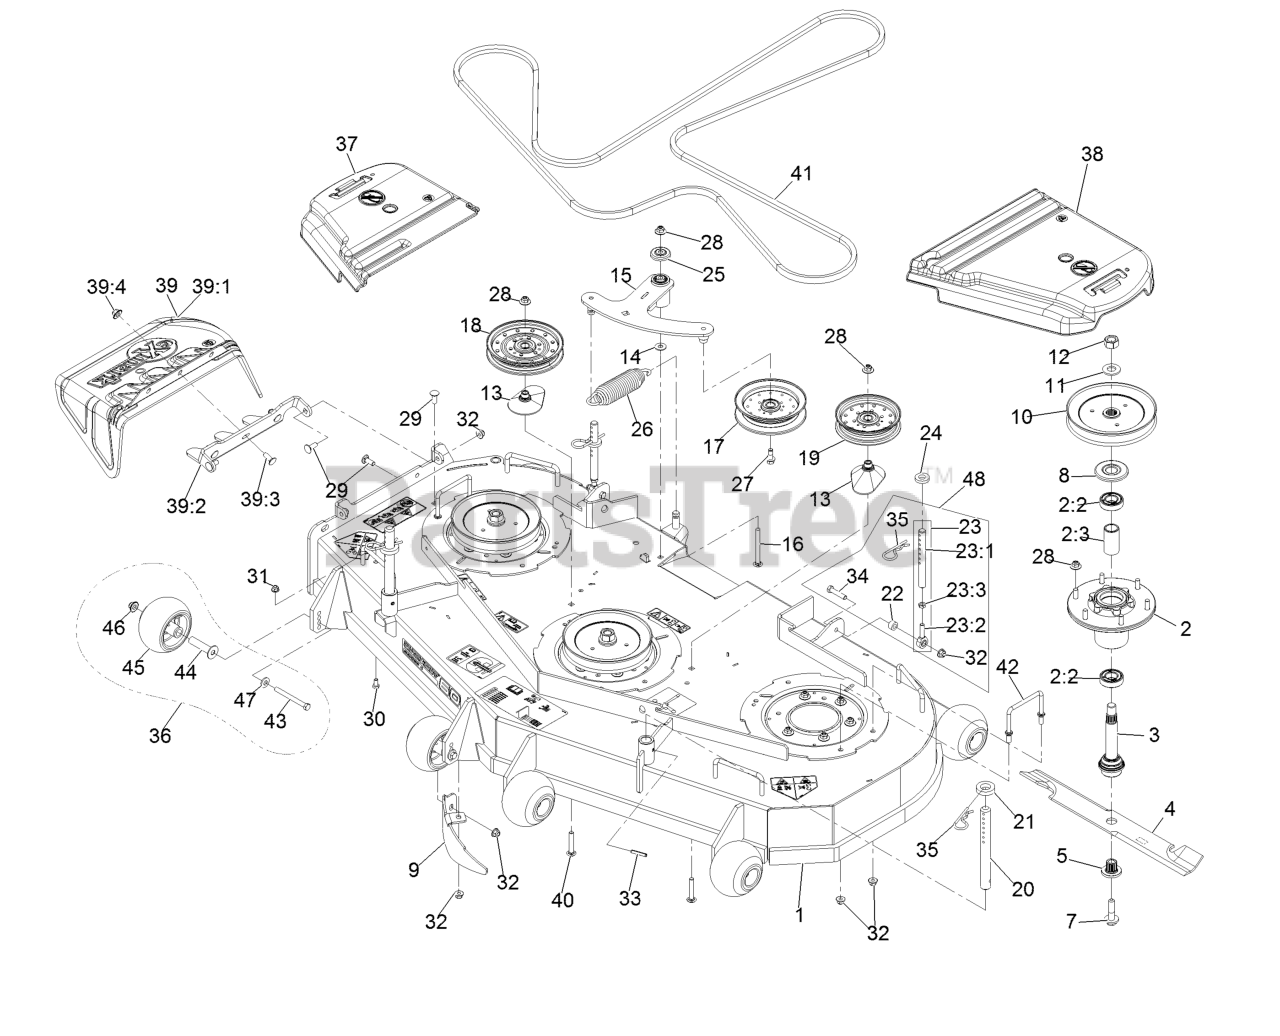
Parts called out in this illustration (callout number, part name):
1	ASM, Deck W/ Decals, 60"
2	ASM-Cutter Hsg With Bearings
2:2	Bearing-Ball
2:3	Spacer-Bearing
3	ASM-Spindle And Seal
4	Blade-Extreme 2, 20.50"
4	Blade, Notched
4	Blade, Mulching
4	Blade, Low Lift
4	Blade, Solid
5	Bushing, Splined
7	Screw-Sems 1/2-20 X 2.19
8	Guard,Bearing Top .989
9	Dogleg - Lz60
10	Sheave,Blade Drive 7.25
11	Washer-Spring Disc 3/4
12	Nut-Hex
13	Spacer-Pulley
14	Washer-3/8 Std
15	ASM, Deck Idler
16	Bolt-Carriage 3/8-16 X 3 3/4
17	Idler-Pulley, Flanged
18	Idler-Pulley, Flat
19	Pulley-Idler, Flat
20	Rod, Deck Support
21	Spacer-Deck Support
23	Link Assy
23:1	Link, Rear Deck Support
23:2	Balljoint
23:3	Nut-Jam 3/8-24
24	Spacer-Blade Drive
25	Guard-Top
26	Spring-Extension
27	Screw-Hfh
28	Nut-Nyloc 3/8-16 Flg
29	Bolt-Carriage 3/8-16 X 1
30	Screw-HH 5/16-18 X 5/8
31	Nut-Nyloc 5/16-18 Flg
32	Nut-Nyloc 3/8-16 Flg
33	Rollpin 1/4 X 1 1/2
34	Screw-HH 3/8-16 X 1 3/4
35	Hairpin-Cotter #206
36	Kit, Anti-Scalp Roller
37	Cover-Belt, RH
38	Cover-Belt, LH
39	ASM,Discharge Chute
39:1	Chute, Discharge
39:2	Bracket,Discharge Chute
39:3	Bolt-Carriage 3/8-16 X 1
39:4	Nut-Nyloc 3/8-16 Flg
40	Bolt-Carriage 3/8-16 X 2 1/4
41	Belt, Deck Drive
42	Wireform-Cover
43	Screw-HH 3/8-16 X 3 3/4 GR 8
44	Axle, Roller
45	Roller-Anti-Scalp
46	Nut-Nyloc 3/8-16 Flg
47	Washer-Spring Disc 3/8
48	Kit, Support Link W/Pin
